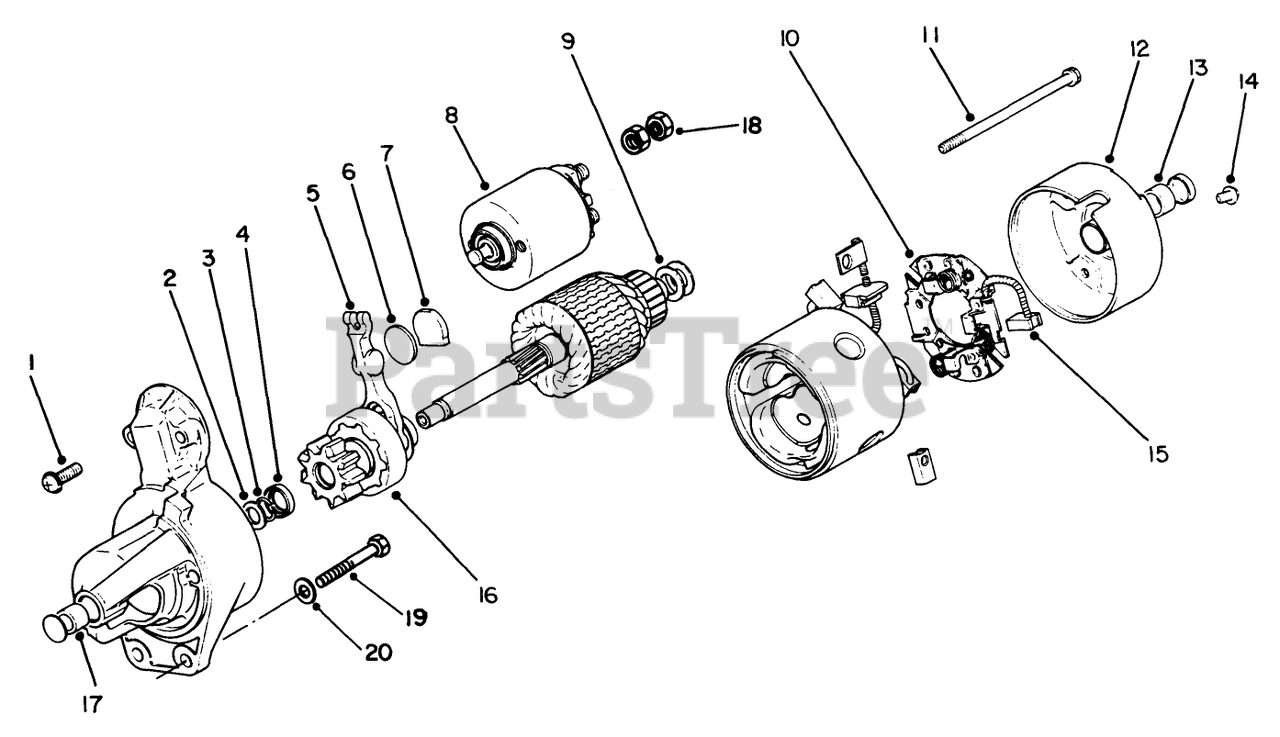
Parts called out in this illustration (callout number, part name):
1	Kit-Hardware (Incl. Ref. #2-4, 9, 11 & 14)
2	Washer
3	Ring-Retainer, Pinion
4	Collar-Stop, Pinion
5	Kit-Lever, Shift (Incl. Ref. #6 & 7)
6	Plate-Wear
7	Plug-Rubber
8	STARTER SOLENOID KIT
9	Shim-Armature
10	Assembly-Holder, Brush (Incl. in each brush)
11	Bolt
12	Kit-Bushing (Incl. Ref. #13)
14	Screw-Holder, Brush
15	Kit-Brush (Incl. 2 neg. & 1 pos. brush)
16	CLUTCH STARTER ASSEMBLY
17	BUSHING
18	NUT-JAM
19	SCREW-HH
20	TINE-HOLLOW, LW 5/8 X 4.75
